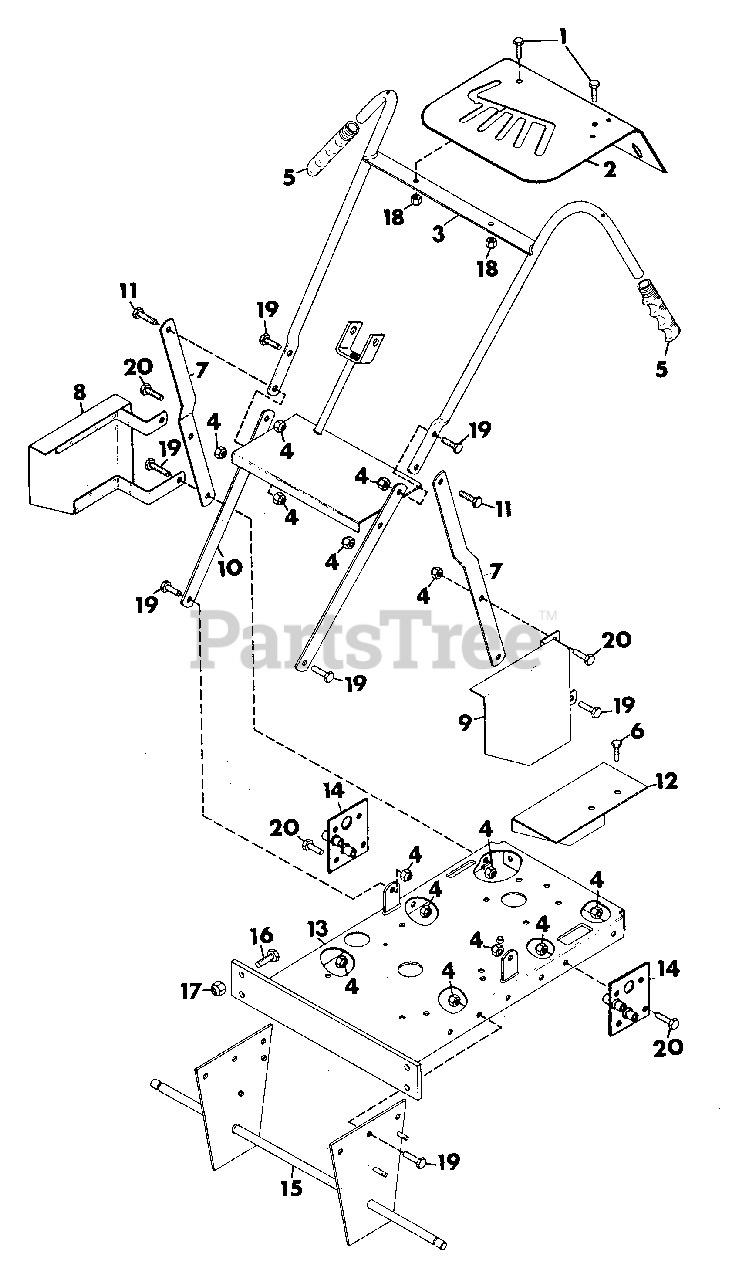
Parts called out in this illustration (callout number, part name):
1	Bolt, Hex 5/16-18x1.00
2	Plate, Instruction
3	Weldment, Handlebar
4	Nut, Lock 3/8-16
5	Grip, Hand
6	Bolt, Self-Tapping 5/16-18x.50
7	Brace, Handlebar Support
8	Weldment, Belt Guard R.H.
9	Weldment, Belt Guard L.H.
10	Weldment, Handle Bar Support
11	Bolt, Hex 3/8-16x1.25
12	Guard, Transmission Chain
13	Weldment, Frame
14	Weldment, Bearing Support L.H.
15	Weldment, Axle
16	Bolt, Hex 1/2-13x1.50
17	Nut, Lock 1/2-13
18	Nut, Lock 5/16-18
19	Bolt, Hex 3/8-16xl.00
20	Bolt, Hex 3/8-16x.75
